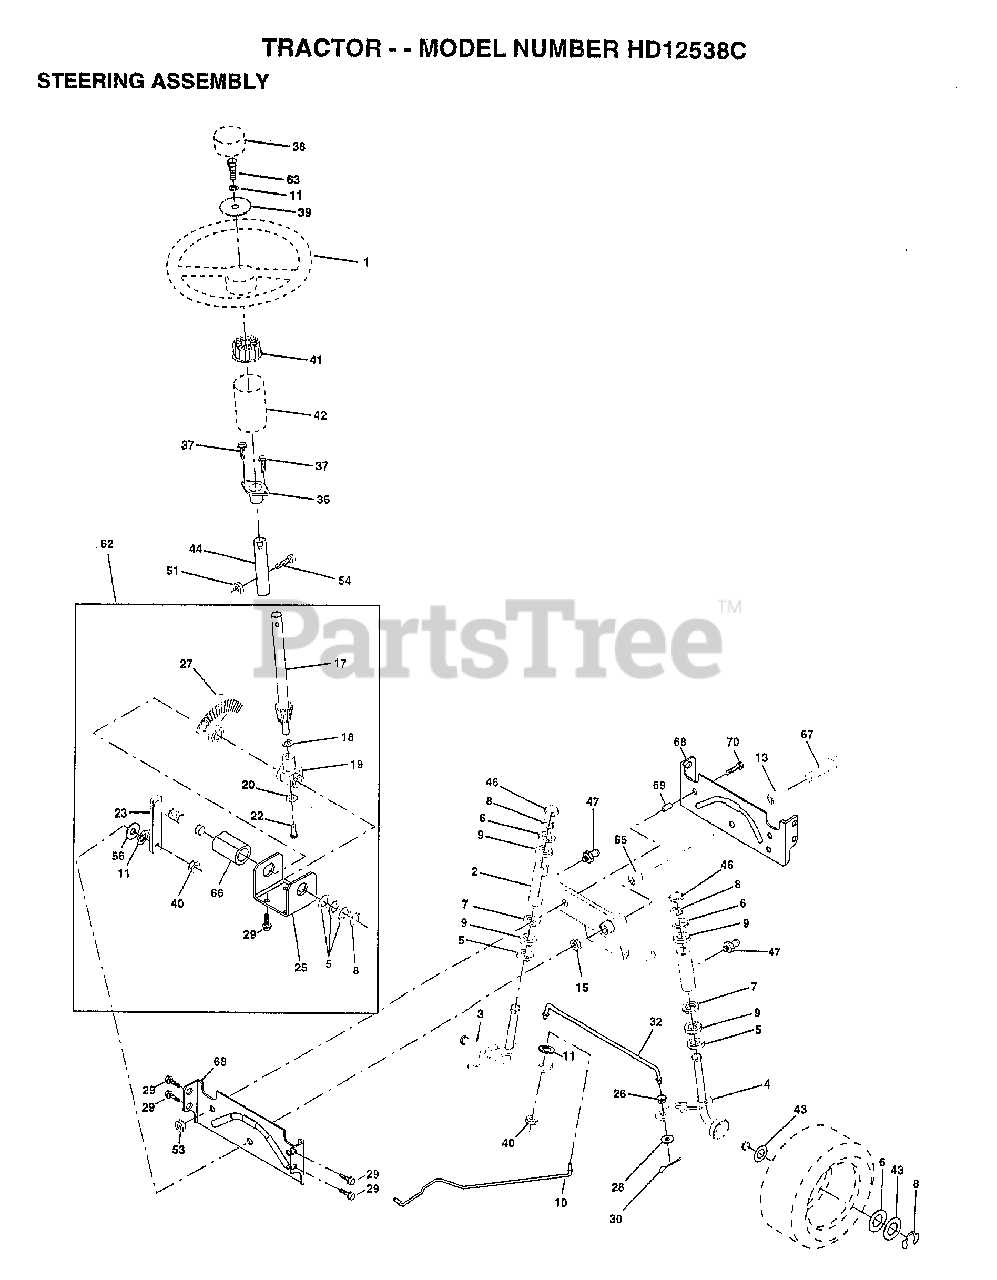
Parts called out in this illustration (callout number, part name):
1	WHEEL STR AYP BLK
2	AXLE ASM
3	SPINDLE.ASM.LH
4	"SPINDLE ASM,RH"
5	WASHER .T
6	WASHER
7	WASHER
8	RING
9	COL. SRTG. BEAR.
10	DRAGLINK-STAMPED
11	LOCKWASHER
13	BEARING AXLE
15	"NUT-LOC,FLANGE LT"
17	SHAFT ASM STEERIN
18	THRUST WASHER
19	SUPPORT.SHAFT
21	LOCKWASHER
22	SCREW.SCKTHD.CAP
25	BRKT-STEERING
26	BUSHING.DRAGLINK
27	GEAR SECTOR
28	WASHER
29	SCREW
30	COTTER PIN
32	TIE ROD
36	BUSHING.STEERING
37	"SCREW-TT,10-32 FL"
38	CAP STEER AYP
39	WASHER T
40	GRIPCO NUT
41	ADAPTER LT
42	BOOT.STEER.PL
43	WASHER
44	EXT SHAFT STEERIN
46	CAP
47	ZERK M
51	NUT
54	BOLT
62	KIT STEERING ASM
63	BOLT
65	SPACER AXLE
66	"BEARING-ARM,PITMA"
67	BOLT
68	BRACE AXLE
69	"SPACER BRCAE,AXLE"
70	BOLT.HEX.3/8-16X2
